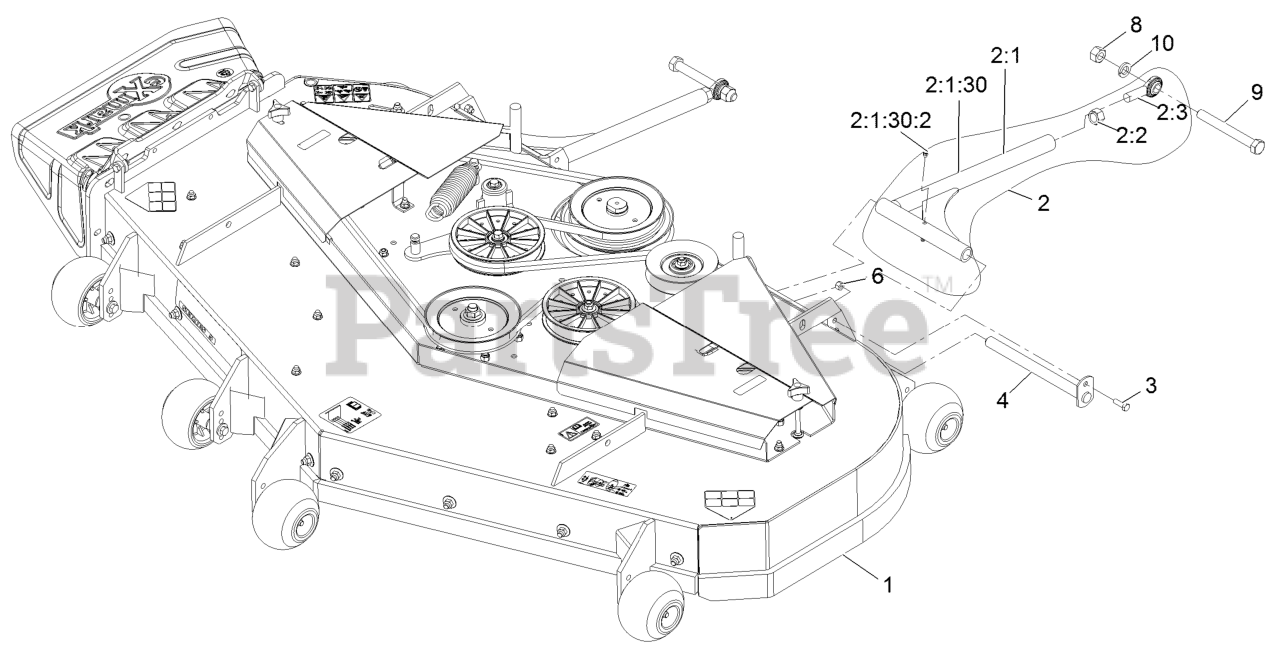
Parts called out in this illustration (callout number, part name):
1	ASM-Deck Complete 725
2	ASM,DECK STRUT XS 72
2:1	WLD,DECK STRUT
2:1:30	Tube And Zerk ASM
2:2	NUT-HEX
2:3	BALLJOINT-SPHERICAL
3	SCREW-HH
4	PIN-STRUT
6	NUT-LOCK, NI
8	NUT-HEX
9	SCREW-HH
10	WASHER-LOCK
